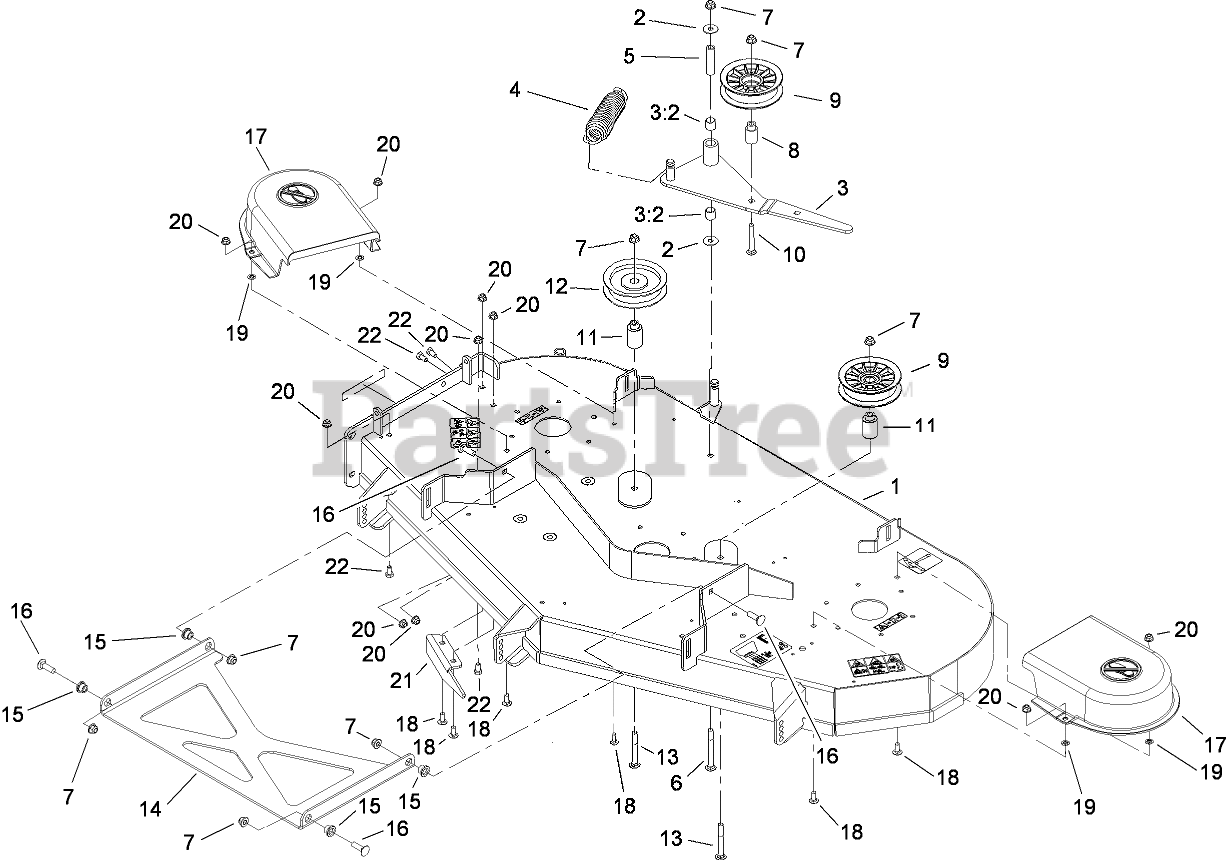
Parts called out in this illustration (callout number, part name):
1	52 INCH DECK ASM
2	WASHER
3	IDLER ARM ASM
3:2	SLEEVE-BEARING
4	Spring-Extension
5	BUSHING-PIVOT, IDLER
6	SCREW-CARR
7	NUT-HF, NI
8	BUSHING-IDLER
9	SHEAVE AND BEARING ASM
10	SCREW-CARR
11	BUSHING-IDLER
12	PULLEY-IDLER
13	BOLT-CARRIAGE
14	STRUT-DECK
15	BUSHING-FLANGED
16	BOLT-CARR
17	SHIELD-BELT
18	SCREW-CARR
19	RING-RETAINING, BOLT
20	NUT-HF, NI
21	BAFFLE-DISCHARGE
22	SCREW-HH
